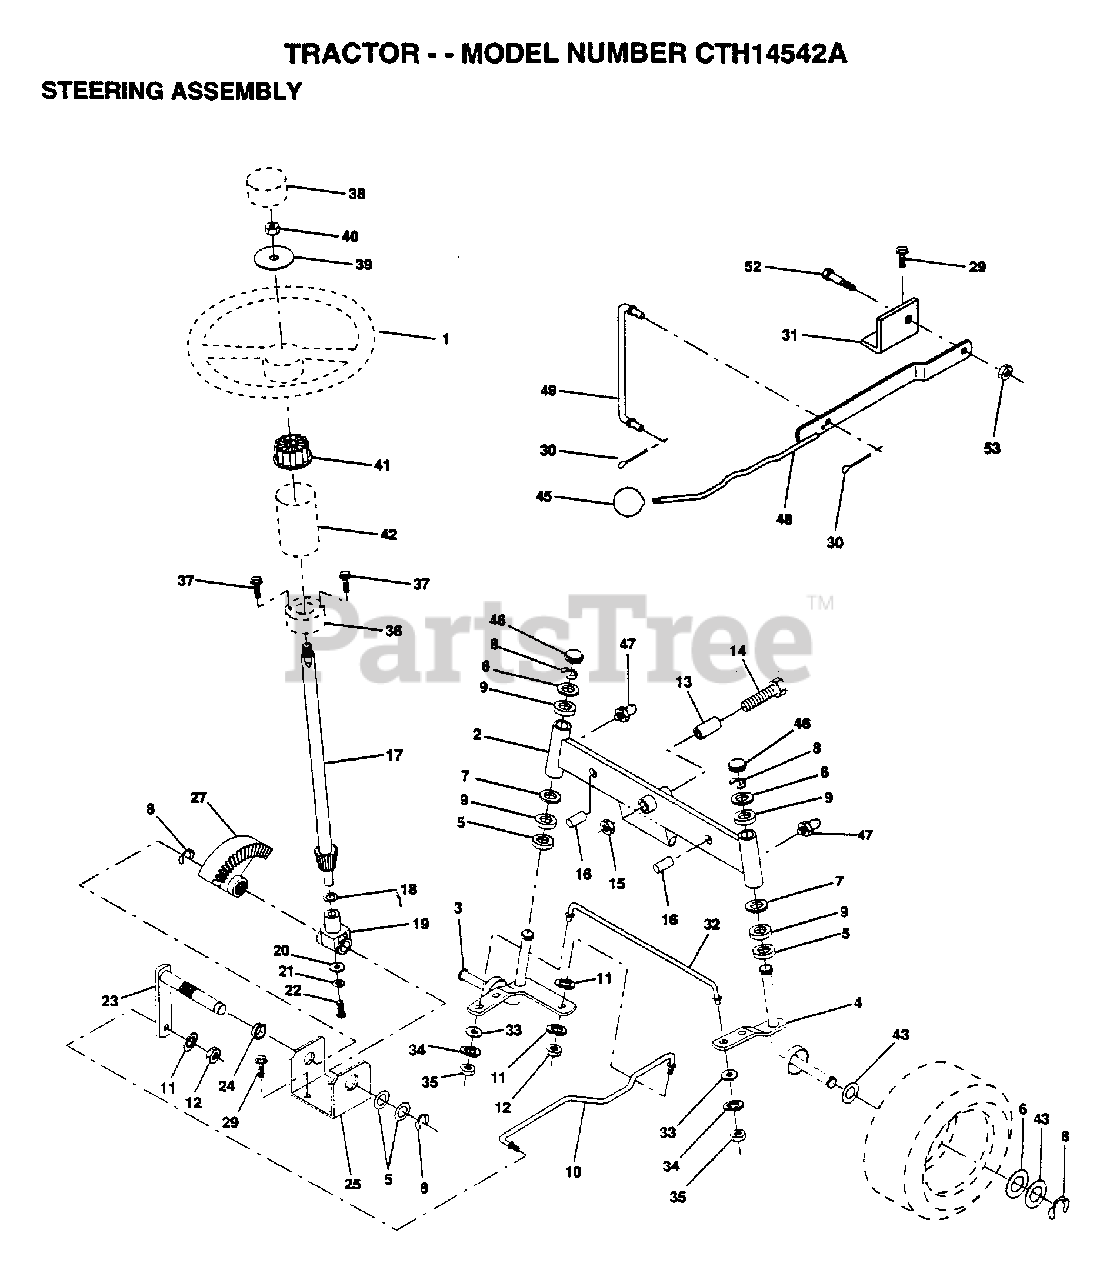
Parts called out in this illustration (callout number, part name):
1	WHEEL STR AYP BLK
2	AXLE ASM FRONT
3	SPINDLE LH
4	SPINDLE RH
5	WASHER .T
6	WASHER
7	WASHER
8	RING
9	COL. SRTG. BEAR.
11	LOCKWASHER
13	BEARING
14	BOLT HEX 5/8-11
15	"NUT-LOC,FLANGE LT"
16	AXLE PIN
17	STEERING SHAFT
18	THRUST WASHER
19	SUPPORT.SHAFT
21	LOCKWASHER
22	"SCREW,SPECIAL"
24	NYLINER T
25	"BRKT,STEERING"
27	GEAR SECTOR
29	SCREW
30	COTTER PIN
31	BRKT.PVT.MAN.LVR.
32	ROD.TIE.19.75
33	WASHER M
34	LOCKWASHER
35	NUT.LOCK.5/16-24
36	BUSHING.STRG.3/4
37	SCREW.10-24X1/2
38	CAP STEER AYP
39	WASHER
41	ADAPTER LT
42	BOOT SHAFT STEER
43	WASHER
45	CONTROL KNOB LT
46	CAP
47	ZERK M
48	LEVER.ASM.CLUTCH
49	LINK CLTCH W/NUTS
52	"BOLT, SHOULDER LT"
